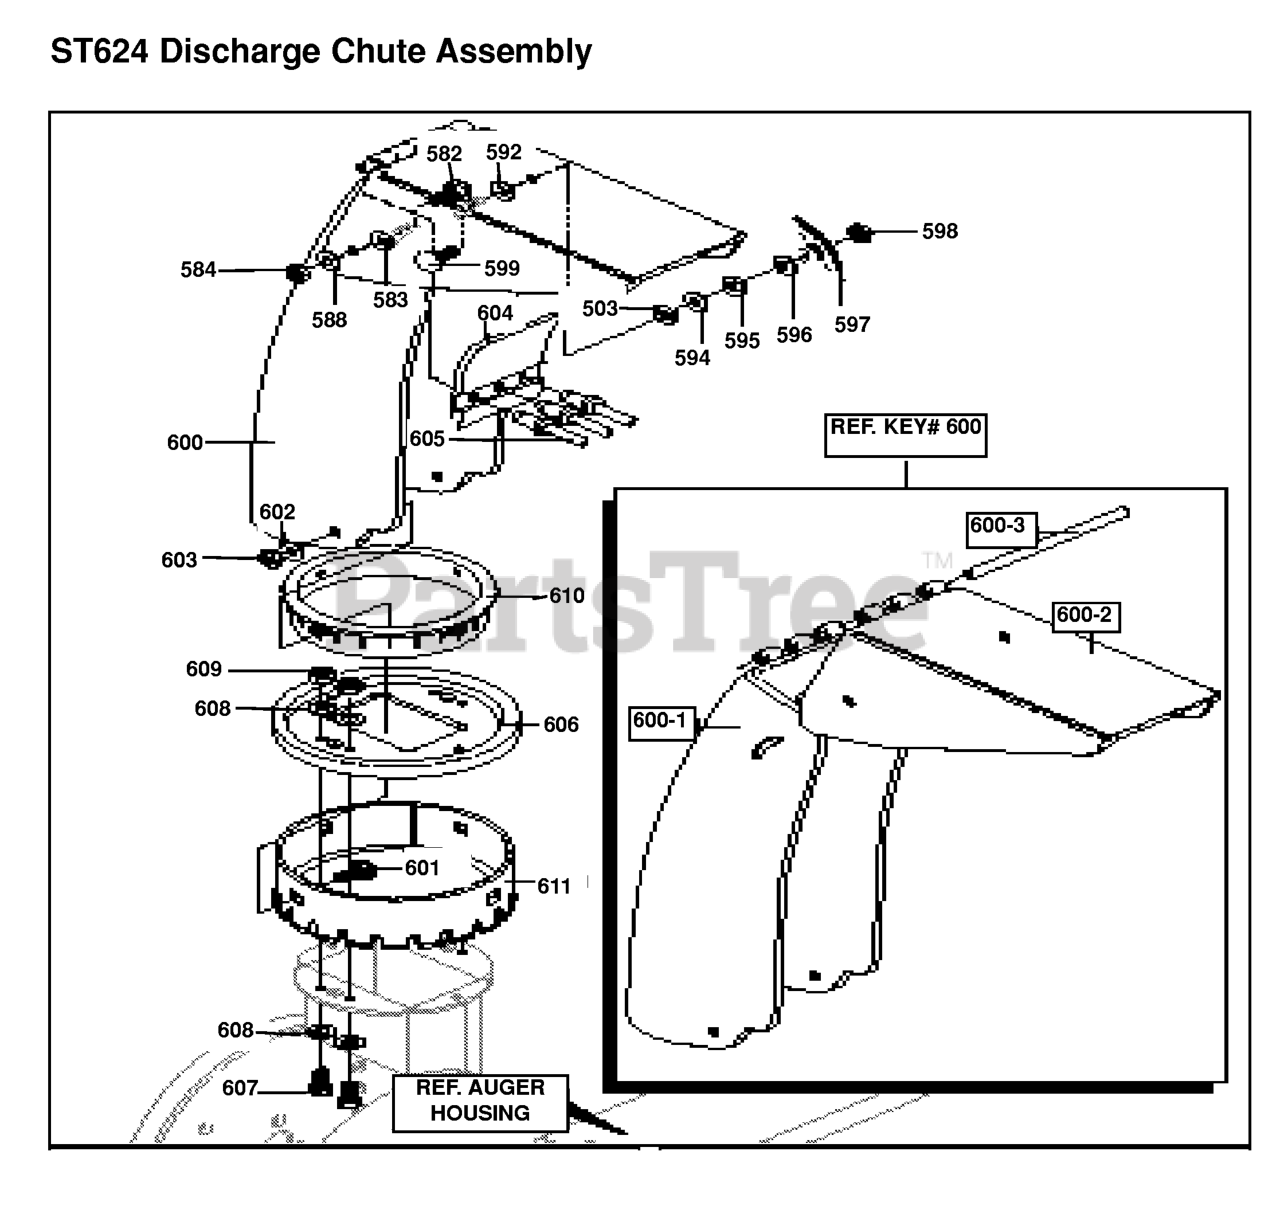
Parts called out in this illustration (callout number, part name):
583	Washer, Pl .438 x .75 x .064
592	Washer, Pl .438 x .75 x .064
594	WASHER, FLAT .344X .69X.
595	WASHER, HVSPTLK .328X.60X
596	WASHER, FLAT .344X .69X.
597	KNOB, W/NUT
598	NUT, 5/16-18 REGHEX
599	BOLT 5/16-18 X 1.00
600	Chute Assembly
600-1	LOWER CHUTE
600-2	UPPER CHUTE
601	Bolt, 5/16-18 x 1.00
602	WASHER, FLAT .344X .69X.
604	Flap, Chute inset
606	COLLAR, CHUTE
607	SCREW, 1/4-20X .75 HHC
608	WASHER, FLAT .281X .63X.
610	RETAINER, RING INNER
611	RETAINER, RING OUTER
